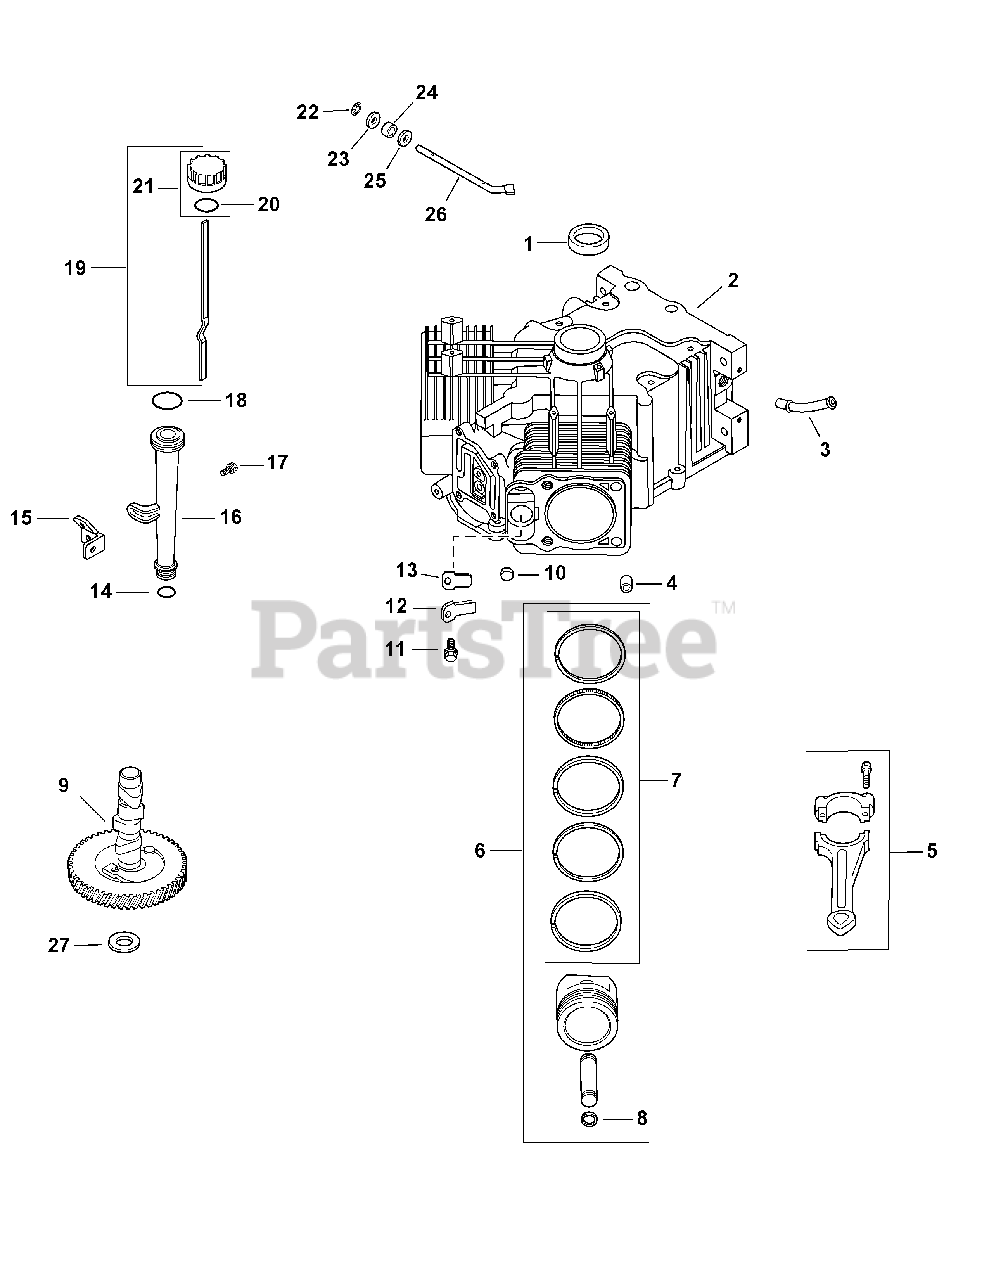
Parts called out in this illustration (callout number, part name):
2	Crankcase
4	Pin, Locating
5	Connecting Rod (STD)
5	Connecting Rod (.25)
6	Kit, Piston w/ Ring (STD) (Includes 7, 8)
6	Kit, Piston w/ Ring (.08)
6	Kit, Piston w/ Ring (.25)
6	Kit, Piston w/ Ring (.50)
7	Ring Set, Piston (STD)
7	Ring Set, Piston (.08)
7	Ring Set, Piston (.25)
7	Ring Set, Piston (.50)
8	Retainer, Piston Pin
9	Kit, Camshaft
11	Screw, Flg Thd Frm M5x0.8x10
12	Retainer, Breather Reed
13	Reed, Breather
14	O-Ring, Lower Oil Fill Tube
15	Bracket, Oil Fill Tube
16	Tube, Oil Fill Assembly
17	Screw, Flg Thd Frm M5x0.8x16
18	O-Ring, Upper Oil Fill Tube
19	Dipstick, Assy (Includes 20, 21)
20	O-Ring, Dipstick
21	Kit, Oil Fill Cap (Yellow)
22	Retainer, Ring
23	Washer, Flat 9MM
24	Seal, Governor Cross Shaft
25	Washer, Flat 1/4" (Bottom)
26	Shaft, Governor Cross
27	Camshaft Shim (White .028")
